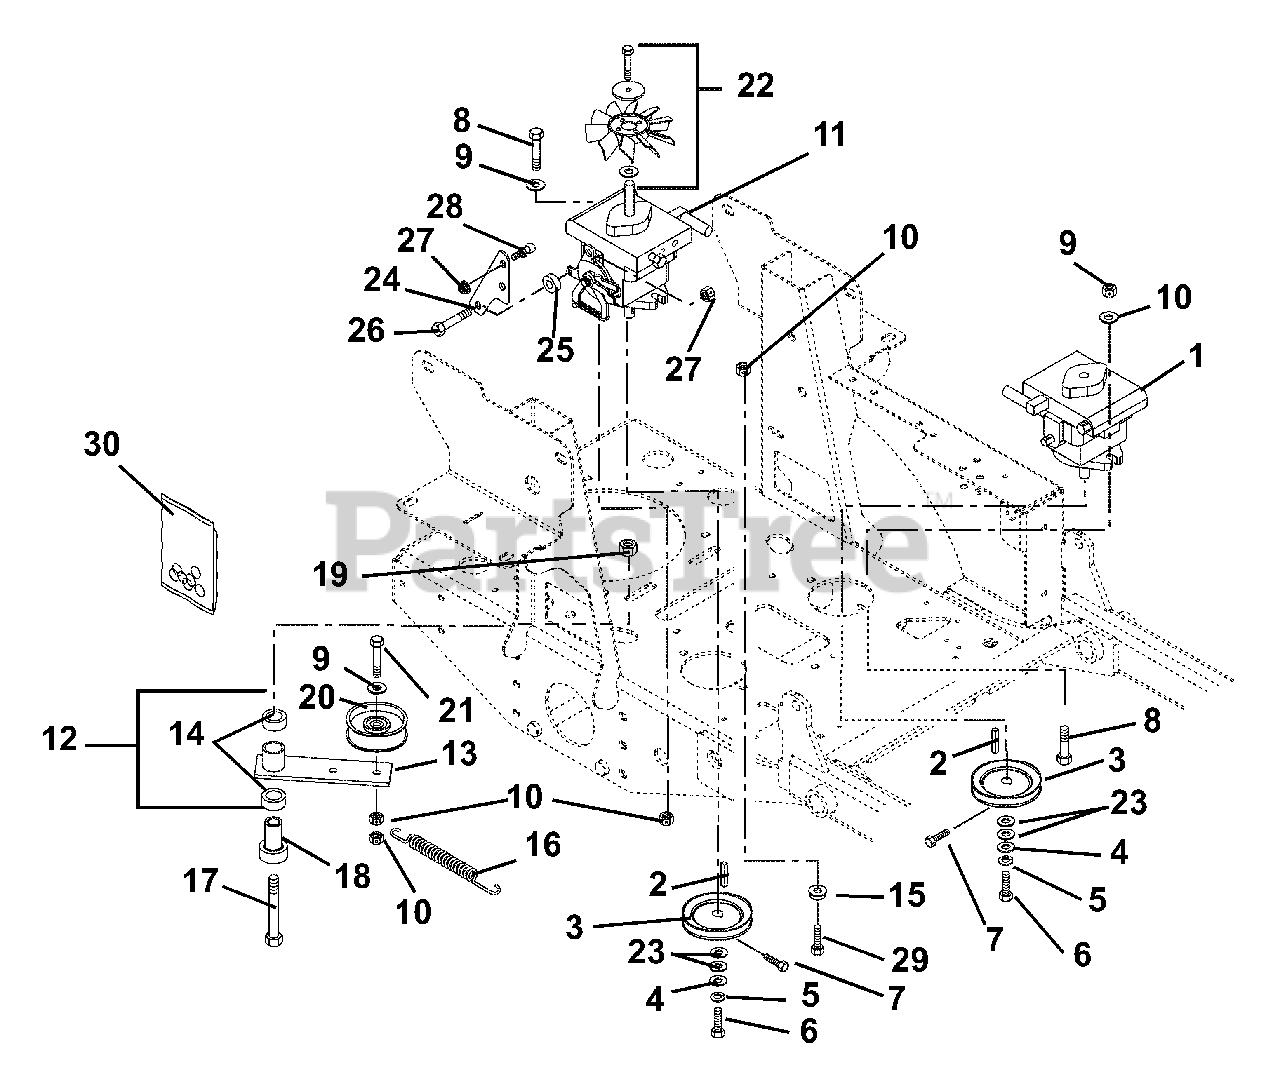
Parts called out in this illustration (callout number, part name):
1	PUMP, HYD BDP-10A (LH)
2	KEY-STR 5MMX25MMX5MM
3	SHEAVE, PUMP .592 X 4.345
4	WSHR-FL-STL .281X1.000X.063
5	@WSHR-LK .25X.062 REG YWZC
6	BLT-HEX M6 X 1.0X12 YWZC
7	BLT-HEX .25-20X.50 GR5 EPOXY
8	@BLT-HEX .38-16X1.25 GR5 YWZC
9	WSHR-FL-STL .390X.75X.125 YWZC
10	@NUT-LK-TOP-FLG .38-16 YWZC
11	PUMP, BDP-10A-441 (THRU SHAFT)
12	ASSEMBLY,IDLER ARM GRD.DRIVE
13	WMT, IDLER ARM GROUND DRIVE
14	BRG, 1.00 X 1.12 X .75
15	@NUT-SPNLK-FLG .375-16 YWZC
16	SPRING, EXTENSION
17	@BLT-HEX .50-13X3.50 GR5 YWZC
18	BEARING, PEDESTAL
19	@NUT-LK-TOP-FLG .50-13 YWZC
20	IDLER, FLAT 4.00X1.06
21	@BLT-HEX .38-16X2.25 GR5 YWZC
22	FAN, COOLING
23	@WSHR-FL-STL.656X1.31X.095 YWZ
24	BRACKET, RTN/DAMPER
25	SPACER .344X1.000X.375
26	@BLT-HEX .31-18X1.25 GR5 YWZC
27	@NUT-LK-TOP-FLG .31-18 YWZC
28	STUD- BALL
29	@BLT-HEX .38-16X3.25 GR5 YWZC
30	KIT, PUMP SEAL
